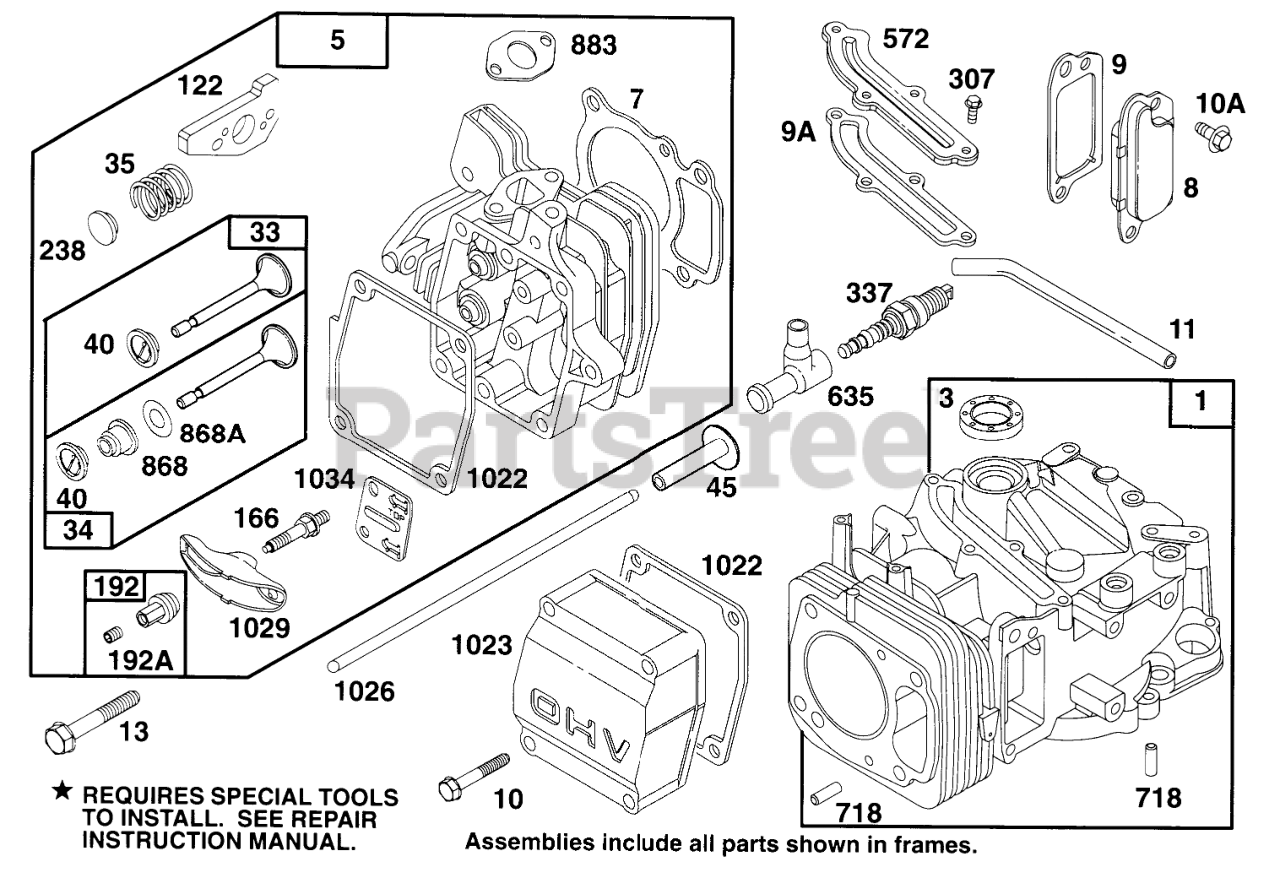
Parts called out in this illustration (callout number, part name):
1	CYLINDER ASSEMBLY
3	SEAL - OIL
5	CYLINDER HEAD
7	CYLINDER HEAD GASKET
8	Breather Assy
9	Gasket-Breather
9A	GASKET-BREATHER
10	HEX HEAD SCREW
10A	HEX HEAD SCREW
11	BREATHER TUBE
13	CYLINDER HEAD SCREW
33	EXHAUST VALVE
34	INTAKE VALVE
35	VALVE SPRING
40	SPRING RETAINER
45	VALVE TAPPET
122	ADAPTER ASSEMBLY
166	ROCKER ARM STUD
192	NUT - HEX SPECIAL
192A	Screw-Set
238	VALVE CAP
307	SCREW - SEM
337	PLUG-SPARK
572	BAFFLE - CYCLINDER
635	ELBOW-PLUG, SPARK
718	DOWEL - SLEEVE
868	SealAssy-Valve
868A	Seal-Valve
883	EXHAUST GASKET
1022	ROCKER COVER GASKET
1023	Cover-Valve
1026	PUSH ROD
1029	ROCKER ARM
1034	PUSH ROD GUIDE
